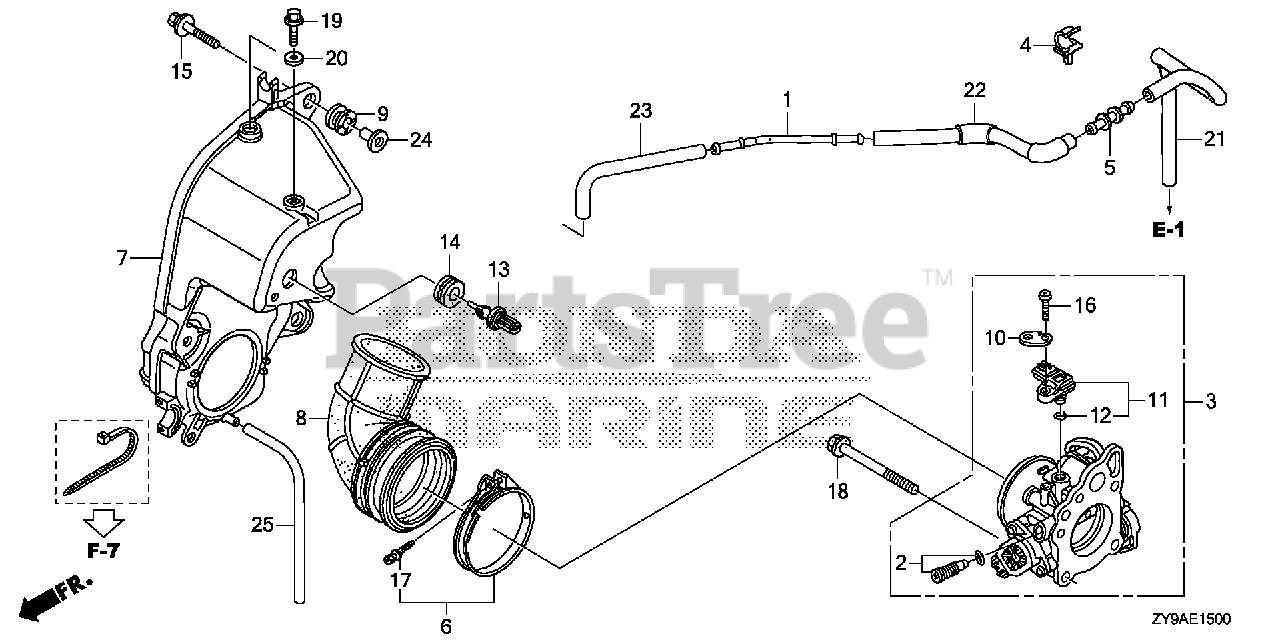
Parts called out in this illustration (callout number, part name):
1	PIPE, BREATHER
3	BODY ASSY., THROTTLE
4	CLAMP B, FUEL TUBE
5	JOINT, FUEL TUBE
6	BAND, AIR FLOW
7	CASE, MUFFLER
8	GROMMET, MUFFLER
9	GROMMET, ELECTRONIC PARTS CASE
10	BRACKET, SENSOR WIRE
11	SENSOR ASSY., MAP
13	SENSOR ASSY., AIR TEMPERATURE
14	GROMMET, TA SENSOR
15	BOLT-WASHER (6X27) (CT200)
16	SCREW, PAN (5X18)
17	BOLT-WASHER (5X30)
18	BOLT, FLANGE (8X60)
19	BOLT, FLANGE (6X25)
20	WASHER, PLAIN (6MM)
21	TUBE A, BREATHER
22	TUBE B, BREATHER
23	TUBE C, BREATHER
24	COLLAR, MODULE IGNITION CONTROL CASE (CDI)
25	BULK HOSE, VINYL (4X7X8000) (4X7X190)
